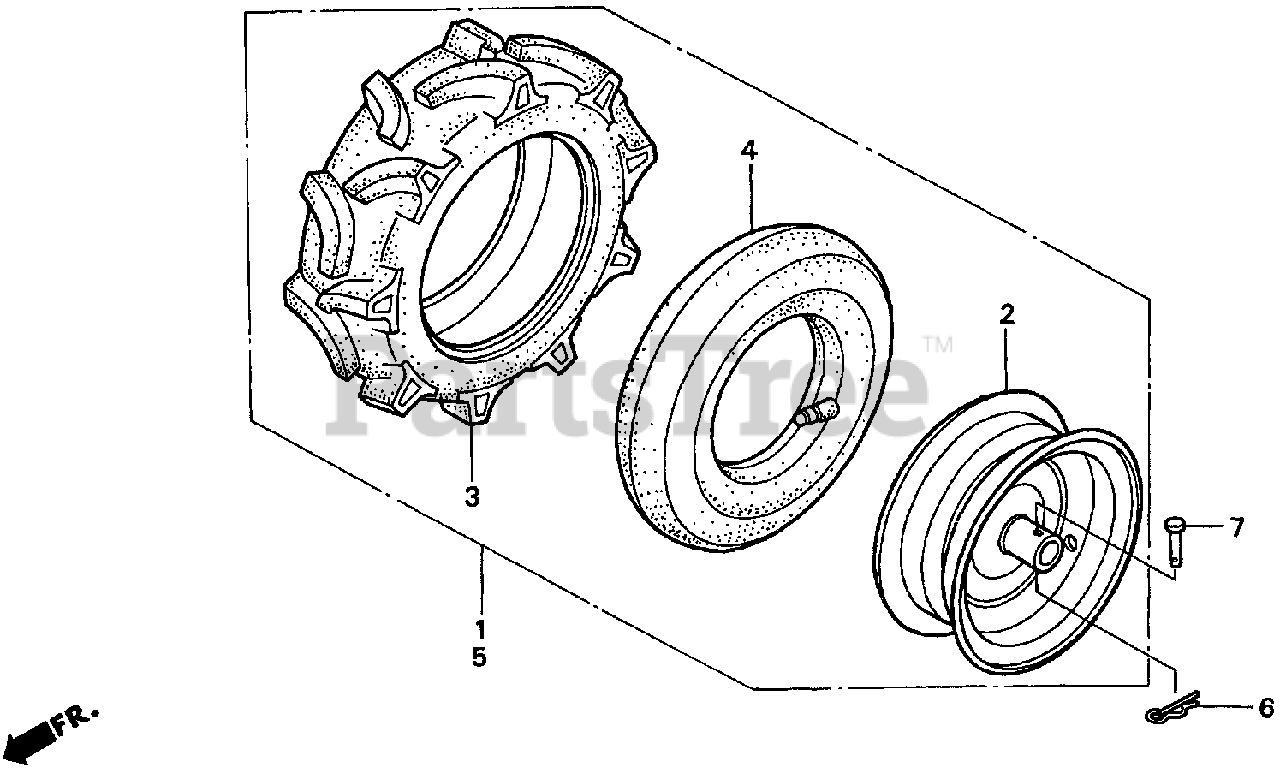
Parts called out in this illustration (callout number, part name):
1	WHEEL ASSY., R. (3.50-7)
3	TIRE (3.50-7)
4	TUBE, TIRE
5	WHEEL ASSY., L. (3.50-7)
6	PIN, LOCK (8MM)
7	PIN (8X32)
